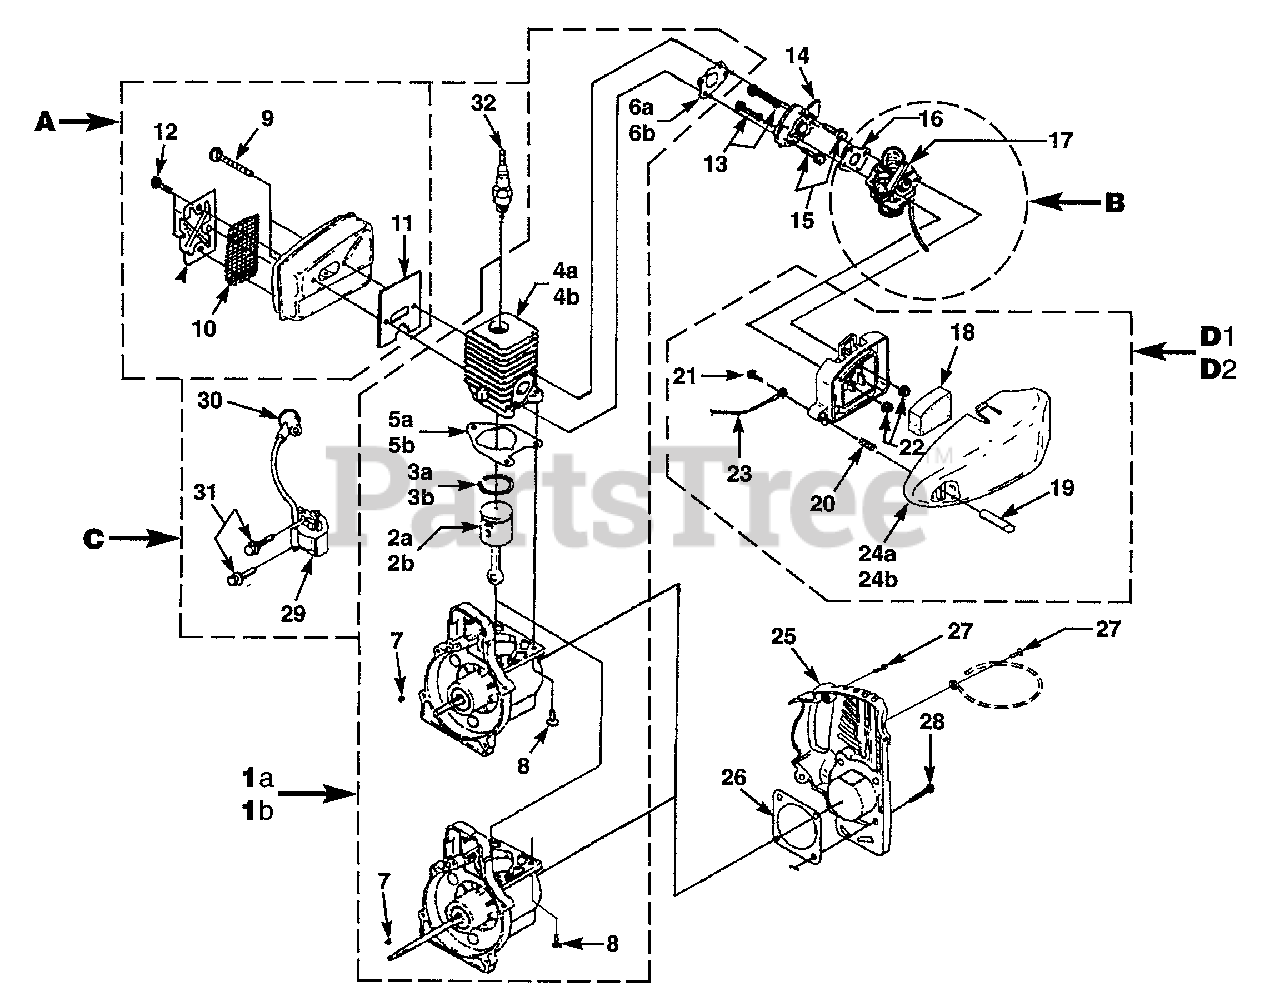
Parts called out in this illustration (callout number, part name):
1A	REPOWER SHORT BLOCK
1B	REPOWER SHORT BLOCK
2A	30CC PISTON & ROD
2B	25CC PISTON & ROD
3A	RING-Piston
3B	RING-Piston
4A	30CC CYLINDER KIT
4B	25CC CYLINDER KIT
5A	GASKET-Cylinder
5B	GASKET-Cylinder
6A	GASKET-Heat Dam
6B	GASKET-Heat Dam
7	KEY-Woodruff
8	SCREW-Thread Form. (10-24 X 3/4")
9	SCREW-Machine (#10-24 X 2")
10	SCREEN-Spark
11	GASKET-Muffler
12	SCREW-Machine-Pan Slotted (8-32 X 3/4")
13	SCREW-Machine (10-24 X 2 1/4")
14	HEAT DAM
15	SCREW-Taptite (10-24 X 1")
16	GASKET-Carburetor
17	LEVER-Choke Rod-(ZAMA)
18	FILTER-Air
19	BUTTON-Switch
20	SPRING-Compression
21	SCREW-Plastite (#6-19 X 1/2")
22	NUT-Hex (10-24)
23	LEAD-Electrical
24A	COVER-Air Filter
24B	COVER-Air Filter
25	CRANKCASE COVER
26	GASKET-Crankcase Cover
27	SCREW-Plastite (#10 X 3/4")
28	SCREW-Taptite (10-24 X 7/8")
29	MODULE-Ignition
30	TERMINAL & COVER
31	SCREW-Taptite (8-32 X 1")
32	SPARK PLUG
A	MUFFLER KIT
B	CARBURETOR
D1	AIR FILTER KIT W/PUSH-BUTTON STOP
D2	AIR FILTER KIT W/O PUSH-BUTTON STOP
C	IGNITION KIT
